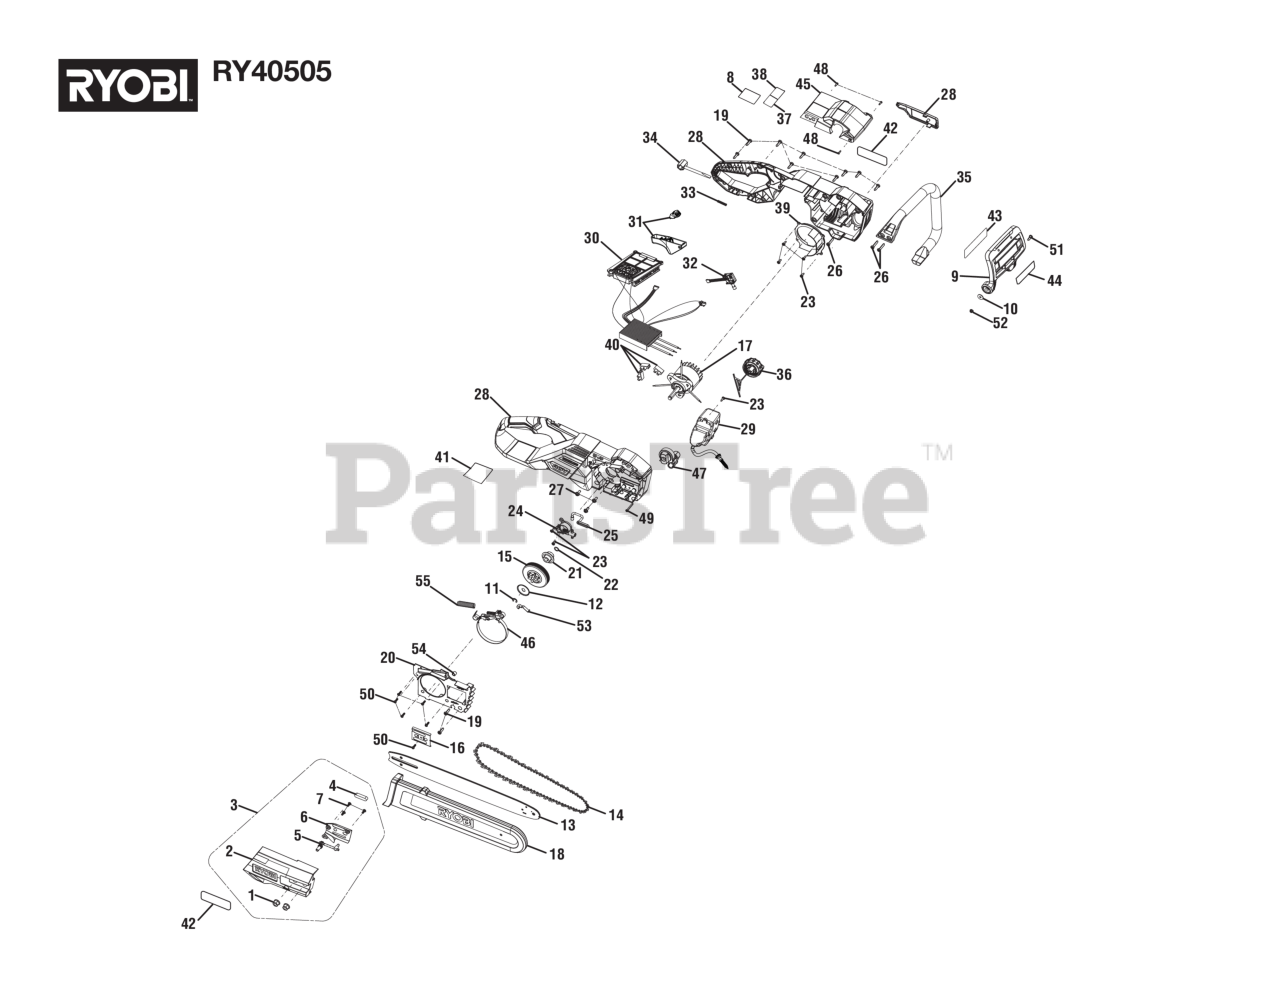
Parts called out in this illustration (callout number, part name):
1	Hex Nut (5/16-18 Flange)
2	Bar Cover
3	Bar Cover Assembly
4	Rubber Plate
5	Driving Adjustment Gear Assembly
6	Guide Plate
7	Screw (M4 x 10 mm, T20 Torx Pan Hd.)
8	Warning Label (Spanish)
9	Guard Assembly
10	Washer (ID5.2 x OD16 x 1.5t)
12	Washer (Special)
13	Bar (16 in.)
14	Chain (16 in.)
15	Sprocket w/ Drum
16	Guide Bar Plate Assembly
19	Screw, Torx T25, M5, Low Carbon Steel,
20	Cover Housing
21	Oil Pump Drive
23	Screw (M4.2 x 12 mm, T20 Torx Pan Hd.)
25	Oil Output Tube
26	Screw (M5 x 25 mm, T25 Torx Pan Hd.)
27	Screw, T25, M5X8, Steel, Black ZincePlat
28	Housing Assembly
29	Oil Tank Assembly
30	Motor Controller, Switch & Battery Connector Assembly
31	Switch Trigger & Lock Out Button Assembly
33	Compression Spring (Trigger Lock)
35	Front Handle
36	Oil Tank Cap
37	Icon Label (Right)
38	Icon Label (Left)
39	Volute Cover
40	Terminal Block w/Screw
41	Data Label
42	HP Logo Label
43	Warning Label
44	40V Brushless Logo Label
45	Top Cover Assembly
46	Brake Band Assembly
47	Chain Brake Assembly
48	Screw (M3 x 10 mm)
49	Screw (M4-18 x 30 mm, T15 Torx Soc. Hd.)
50	Screw, T20, M4-18X12, Low Carbon Steel,
51	Screw (M5 x 15 mm, T25 Torx Hd.)
54	Hand Guard Insert
